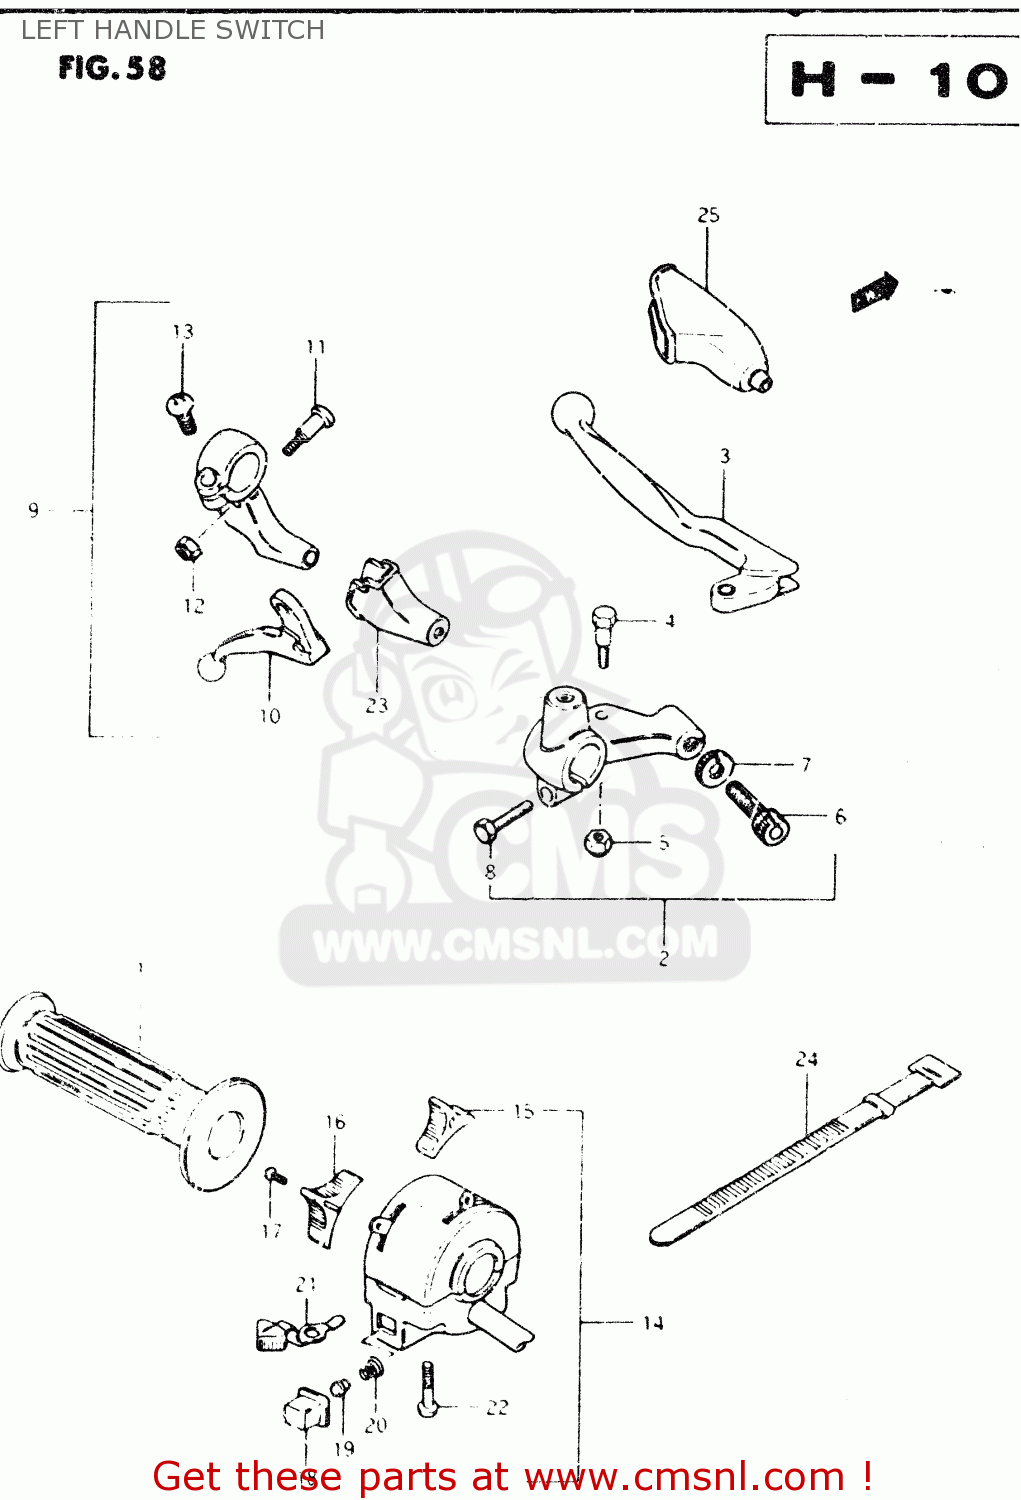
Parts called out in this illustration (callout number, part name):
1	GRIP,L
2	LEVER ASSEMBLY,CLUTCH
3	LEVER,CLUTCH
4	BOLT,LEVER
5	NUT 6MM
6	ADJUSTER,CABLE
7	NUT,CABLE ADJUSTER
8	BOLT,CLUTCH LEVER HOLDER
9	LEVER ASSEMBLY,DECOMPRESSION
10	LEVER,DECOMP
11	BOLT,LEVER
12	NUT
13	SCREW
14	SWITCH ASSY, HANDLE LH
15	KNOB,LIGHTING SWITCH
16	KNOB,DIMMER SWITCH
17	SCREW
18	BUTTON,HORN
19	CONTACT
20	SPRING
21	KNOB,TURNSIGNAL
22	SCREW
23	COVER,DECOMP LEVER DUST
24	CLAMP(L:120)
25	COVER,CLUTCH LEVER
